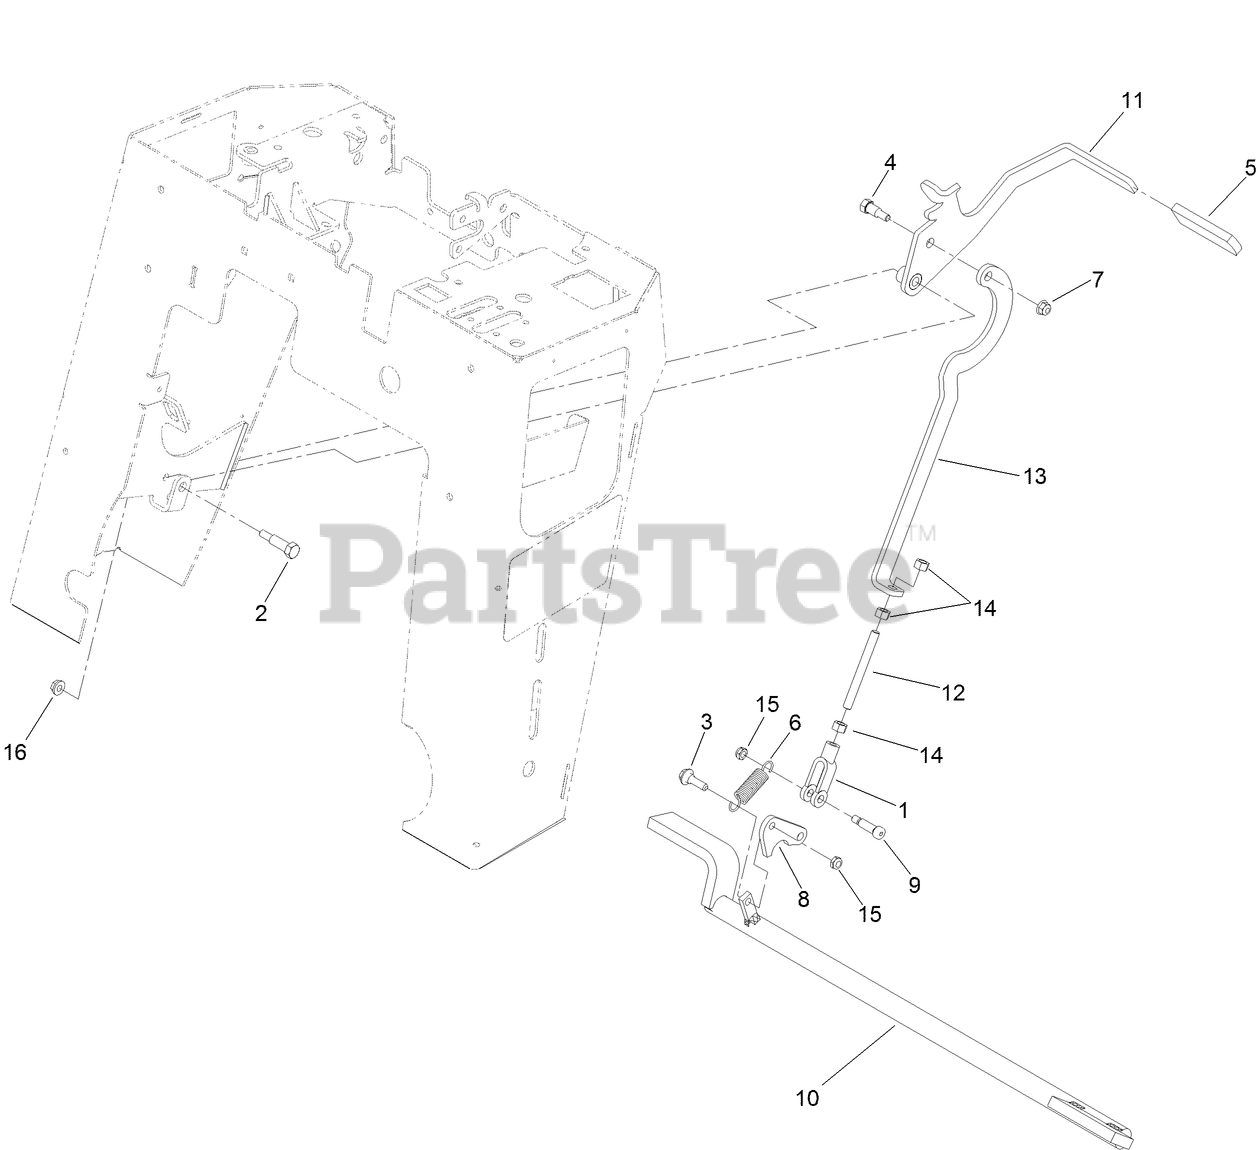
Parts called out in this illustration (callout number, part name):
1	YOKE-LINKAGE, BRAKE
2	SCREW-SHOULDER, HH
3	SCREW-SHOULDER
4	BOLT-SHOULDER
5	GRIP-HANDLE
6	SPRING-IDLER
7	NUT-HF, NI
8	LINK-MOUNTING
9	BOLT-SHOULDER
10	BRAKE BAR ASM
11	BRAKE HANDLE ASM
12	ROD-THREADED
13	PLATE-BRAKE
14	NUT-HEX
15	NUT-LOCK, NI
16	NUT-HF
